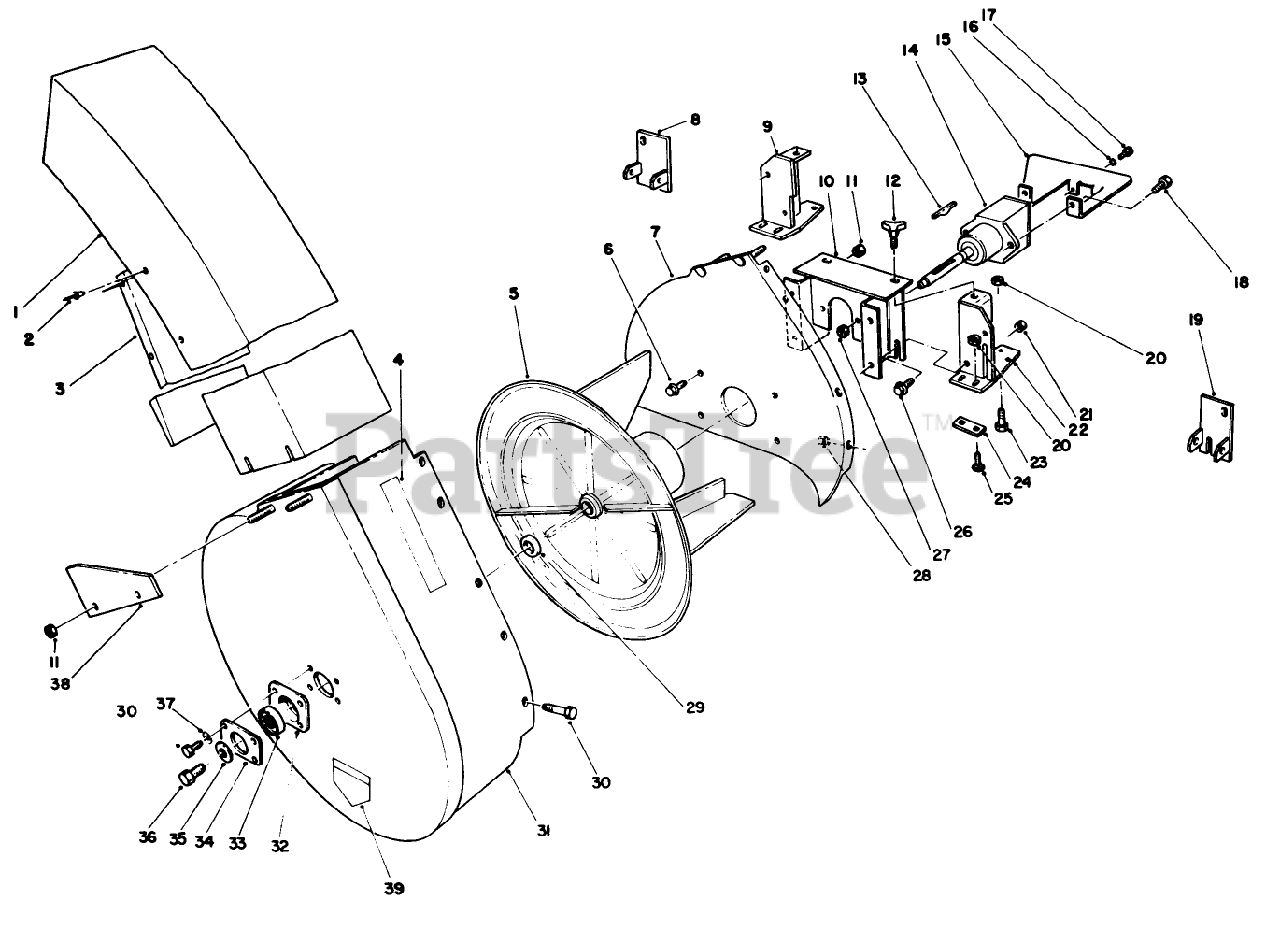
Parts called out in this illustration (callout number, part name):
1	Assembly-Chute (Incl. Ref. #2 & 3)
3	Deflector-Chute
4	DECAL
5	Impeller
6	SCREW-HHF
7	Mounting Plate
8	Bracket-Deflector L.H.
9	LH BRACKET ASM
10	Blower Mount
11	NUT-LOCK, NI
14	Asm-Gear Box
15	Cover-Gear Box
16	WASHER-LOCK, EXT
18	SCREW-HH
19	Bracket-Deflector R.H.
20	NUT-LOCK, CONE
21	NUT-JAM
22	RH BRACKET ASM
23	SCREW-HH
24	Plate-Bracket
25	BOLT-CARR
26	SCREW-HHF
27	NUT-LOCK, NI
28	NUT-LOCK, NI
29	SPACER-BEARING
30	SCREW-HH
31	Housing-Blower (Incl. Ref. #4 & 39)
31	NUT-HEX, SIDE DEFORM
32	CUP-BEARING
33	BEARING-BALL
34	Cover-Plate
35	SPACER
36	SCREW-HH, LOCK
37	WASHER-LOCK
38	Bracket
39	DECAL-DANGER
